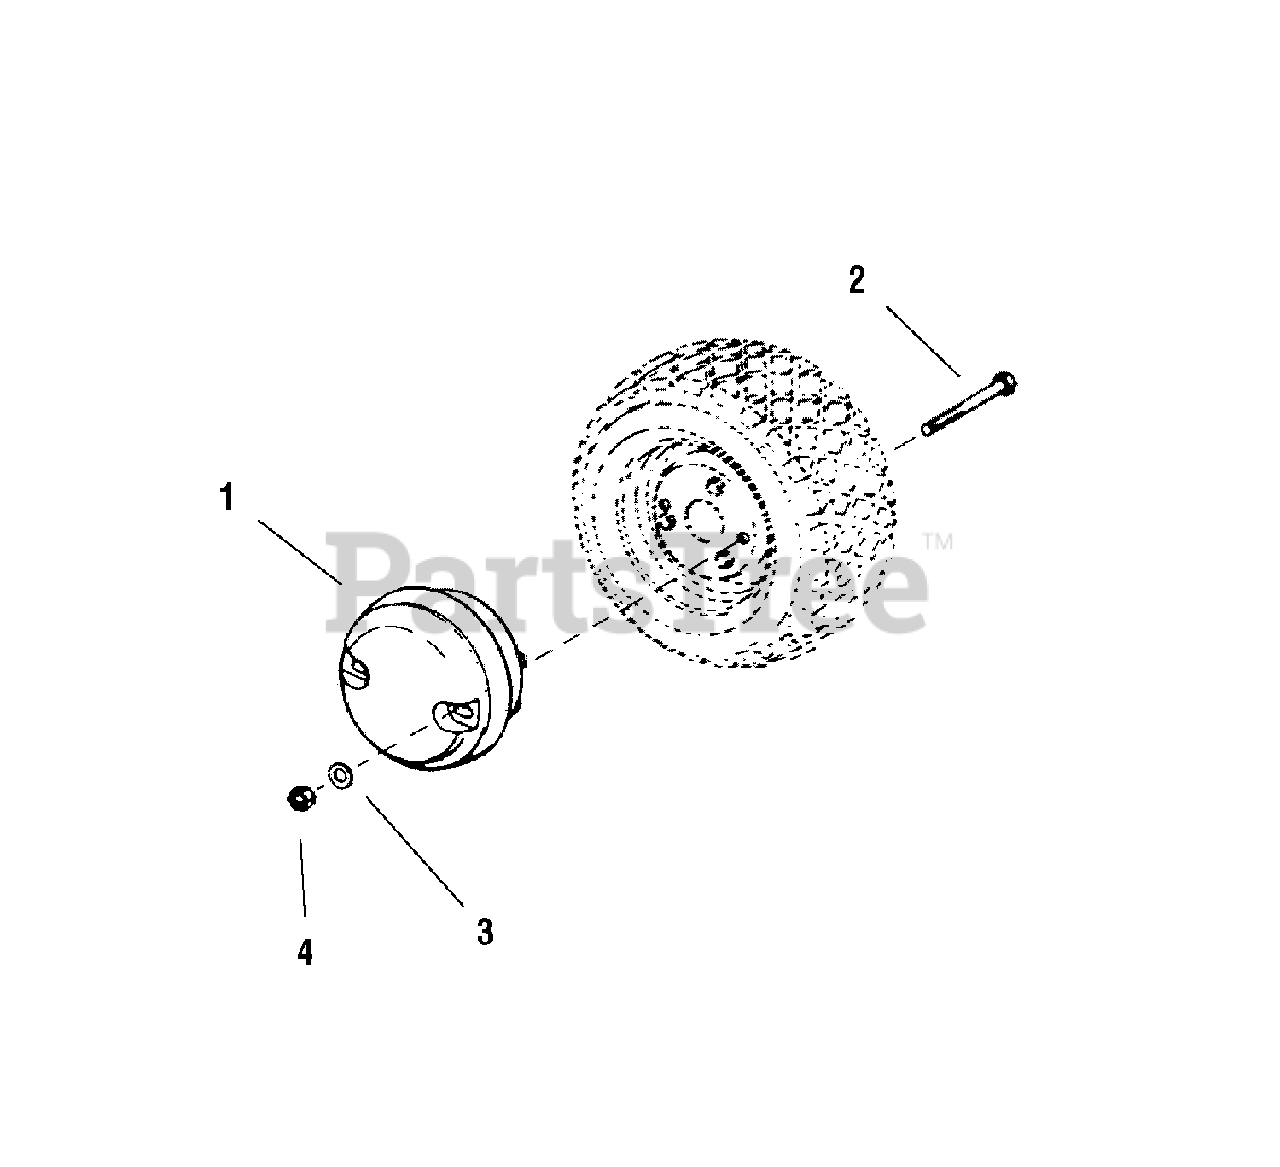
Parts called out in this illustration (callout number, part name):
1	WEIGHT, Wheel
2	CAPSCREW, Hex, 3/8-16 x 4-1/4
3	WASHER, Flat, 3/8
4	NUT, Hex, 3/8-16
